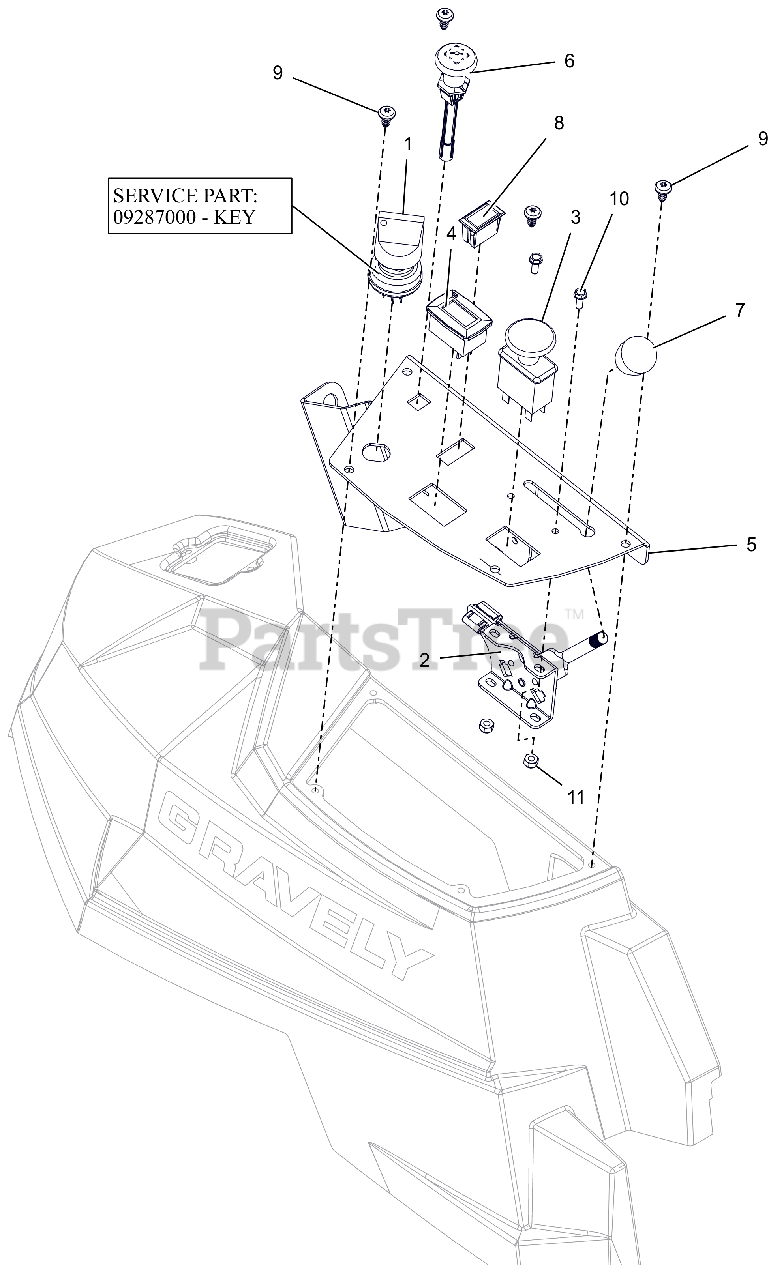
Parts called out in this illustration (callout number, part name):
1	SWITCH, IGNITION
1	KEY, W/ SHIELD
2	CABLE, PRO THROTTLE CONTROL
3	SWITCH, CLUTCH
4	METER, HOUR W/MAINTENANCE
5	PANEL, HD CONTROL
6	CABLE - CHOKE, SNAP-IN
7	KNOB-CONTROL-BLACK .38-16X.50
8	SWITCH,BLANK
9	SCR-PAN .25-15X.50 6L H/LZB500
10	BLT, HWH #10-24X.50 ZCC
11	NUT-LK-NYL #10-24 G2 ZCC
